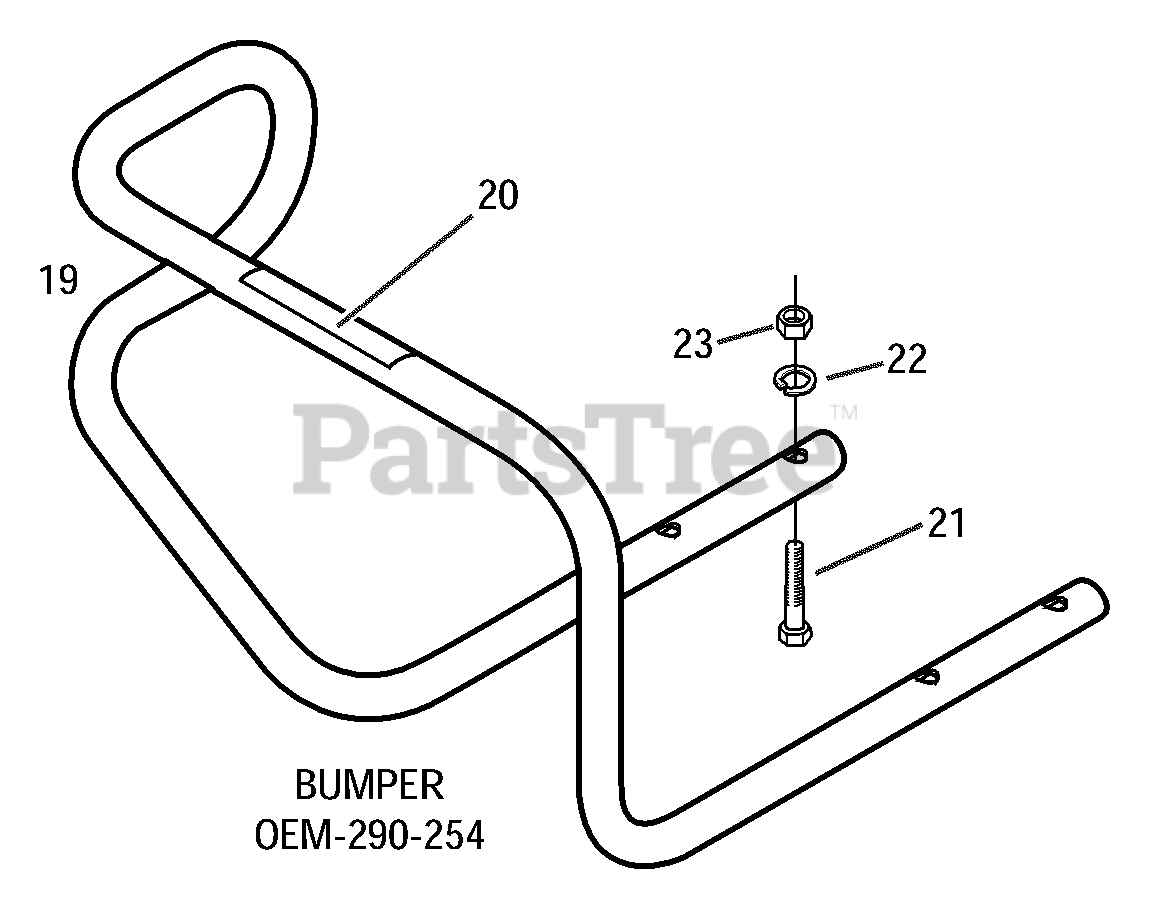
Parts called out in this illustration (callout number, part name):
20	Decal - Caution
21	Screw-hex hd., 5/16-18 x 2-1/4
22	Lockwasher-5/16
23	Nut-hex, 5/16-18
